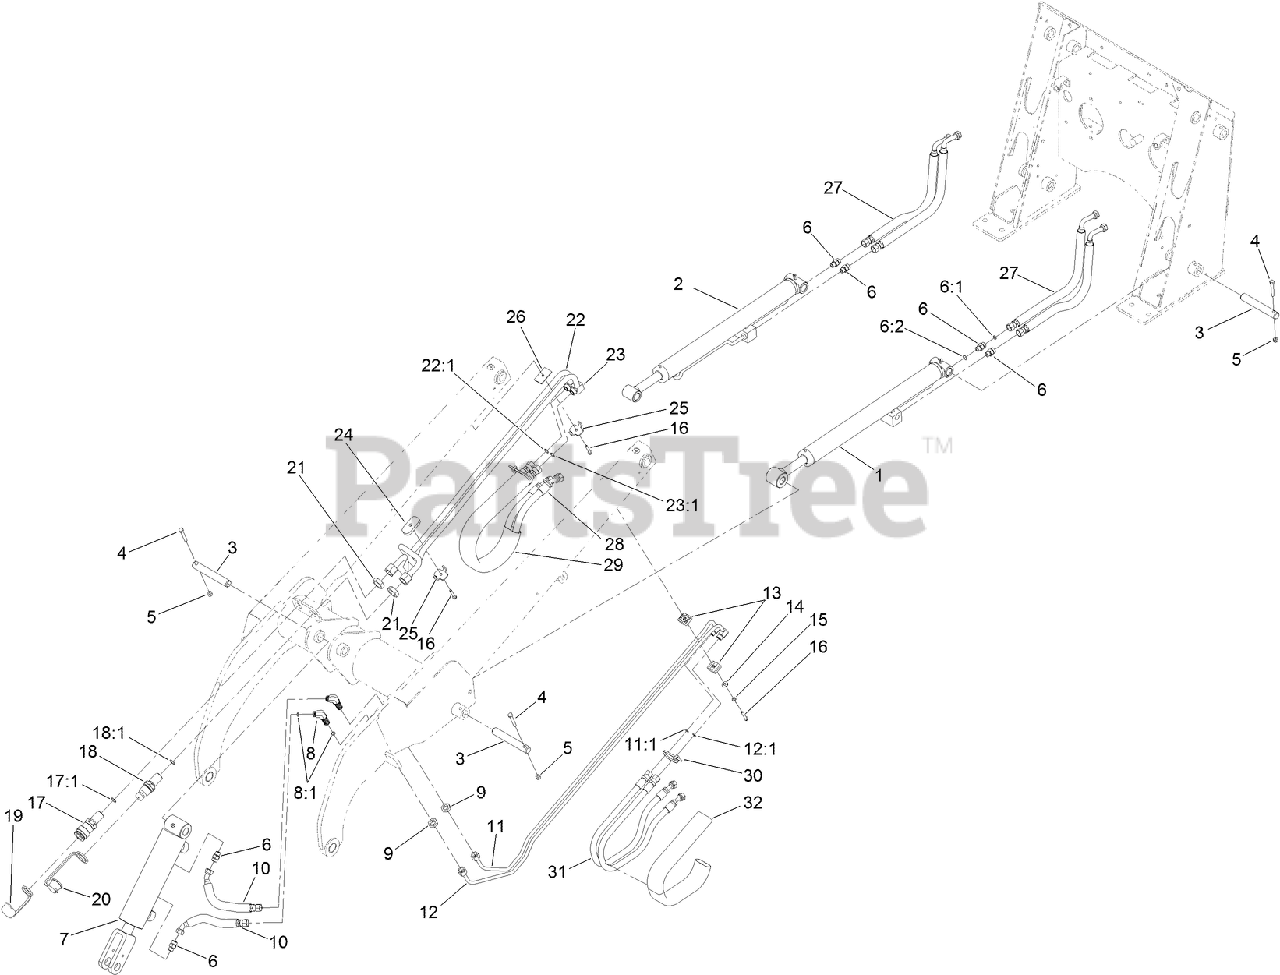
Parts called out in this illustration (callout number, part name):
1	LH HYD CYL ASM
2	RH HYD CYL ASM
3	PIN-LOCKING
4	SCREW-HH
5	NUT-LOCK, NI
6	FITTING-STRAIGHT
6:1	O-RING
6:2	O-RING
7	HYD CYL ASM
8	UNION-BULKHEAD
8:1	O-RING
9	NUT-LOCK
10	HOSE-HYD
11	HYD TUBE ASM
11:1	O-RING
12	HYD TUBE ASM
12:1	O-RING
13	CLAMP-TUBE
14	WASHER-FLAT
15	WASHER-LOCK
16	SCREW-HWH
17	BULKHEAD COUPLER ASM
17:1	O-RING
18	BULKHEAD NIPPLE ASM
18:1	O-RING
19	CAP-DUST, COUPLER
20	CAP-DUST, NIPPLE
21	NUT-LOCK, BULKHEAD
22	HYD TUBE ASM
22:1	O-RING
23	HYD TUBE ASM
23:1	O-RING
24	PLATE-HARDLINE
25	PLATE-CLAMP, TUBE
26	SPACER-HARDLINE
27	HOSE-HYD
28	HOSE-HYD
29	SLEEVE-PROTECTIVE
30	TIE-CABLE
31	HOSE-HYD
32	SLEEVE-PROTECTIVE
